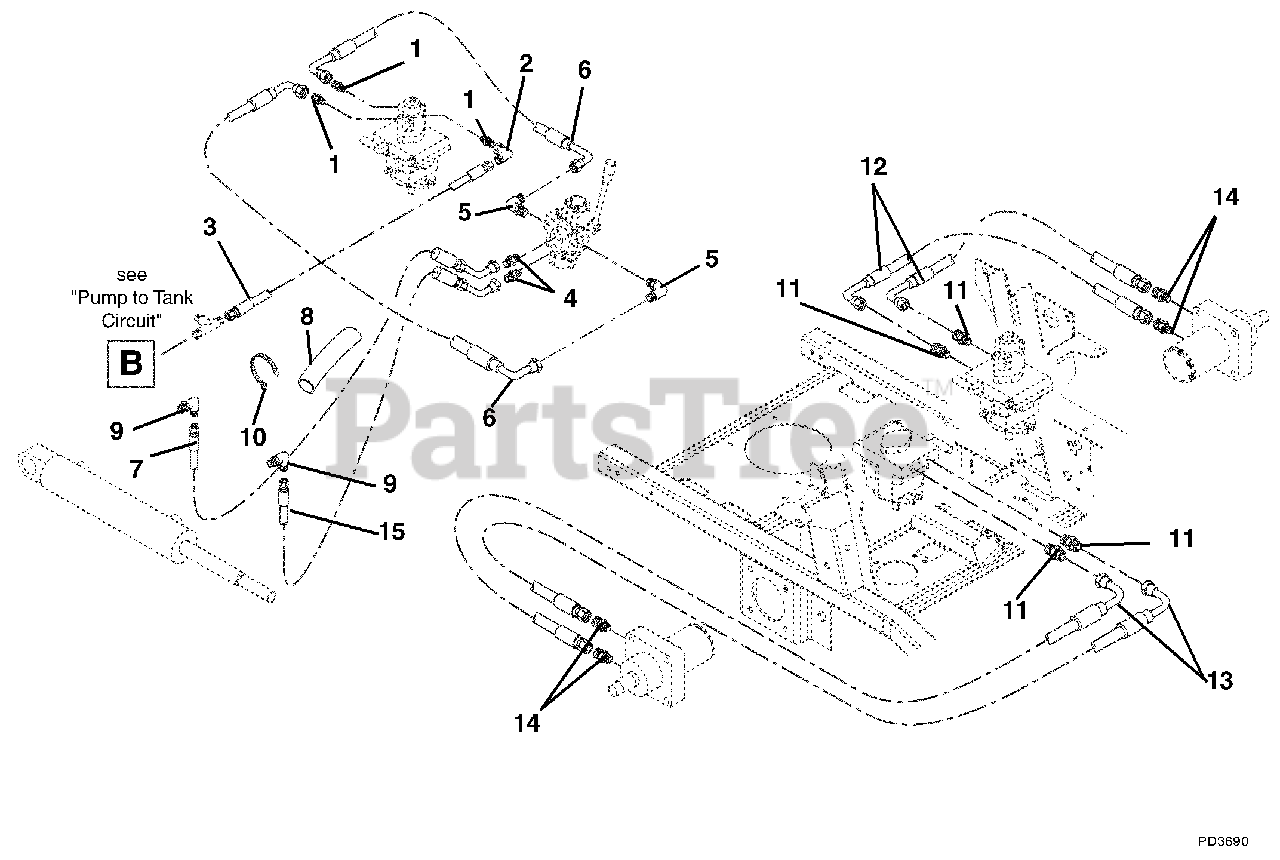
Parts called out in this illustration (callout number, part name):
2	Adapter
3	Hose-Hydraulic
4	Fitting, Hydraulic
5	Fitting, Hydraulic Elbow
6	Hose Hydraulic
7	Hose-Hydraulic
8	Sleeve Protective 24"
9	Fitting, Hydraulic Elbow
10	Cable Tie
11	Adapter-Hydraulic
12	Hose-Hydraulic
13	Hose-Hydraulic
14	Adapter-Hydraulic
15	Hose-Hydraulic
